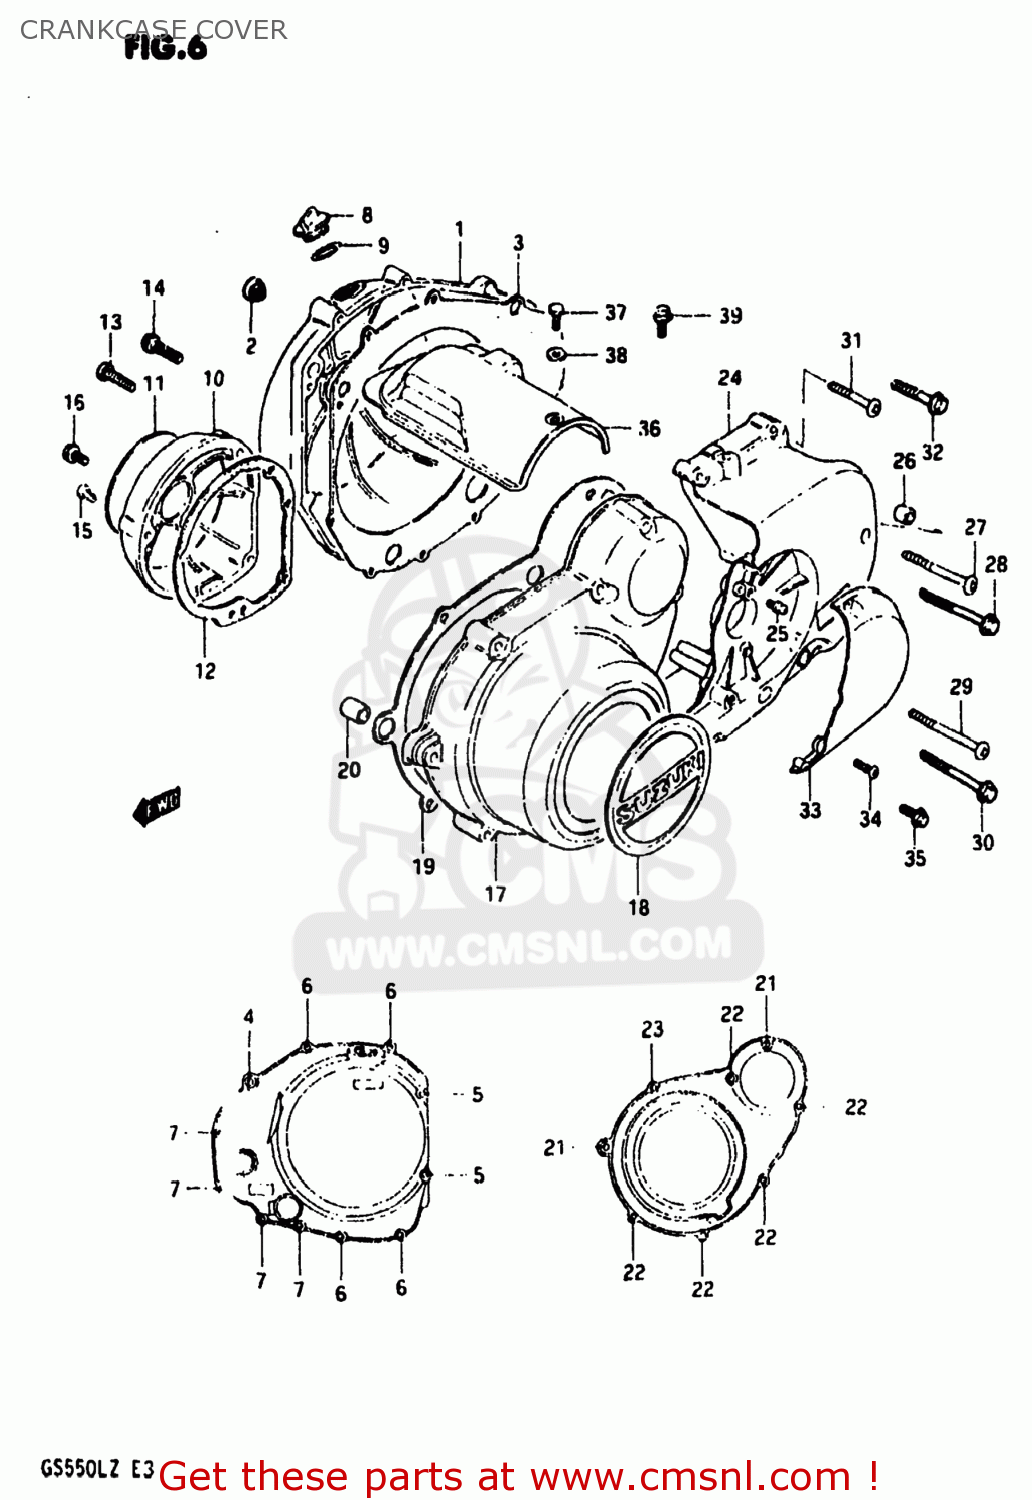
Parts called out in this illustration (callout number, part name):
1	COVER,CLUTCH
2	LENS,OIL LEVEL CHECK
3	GASKET,CLUTCH COVER (MCA)
4	BOLT (6X35)
5	SCREW
6	BOLT
7	SCREW
8	CAP
9	O RING(D:2.2,ID:32)
10	COVER,CONTACT BREAKER
11	EMBLEM,CONTACT BREAKER COVER
12	GASKET,CONTACT BREAKER COVER (NAS)
13	SCREW
14	BOLT (5*30)
15	SCREW
16	BOLT 5X16
17	COVER
18	EMBLEM,MAGNETO COVER
19	GASKET,MAGNETO COVER (MCA)
20	PIN
21	BOLT
22	SCREW
23	BOLT (6X35)
24	CRANKCASE SET
25	NIPPLE
26	PIN
27	SCREW
28	BOLT
29	SCREW 6X80
30	BOLT
31	SCREW 6X30
32	BOLT (6X30)
33	CAP,CLUTCH RELEASE ADJUST
34	SCREW
35	BOLT 5X16
36	COVER,STARTER MOTOR
37	BOLT
38	WASHER
39	BOLT (5*8)
